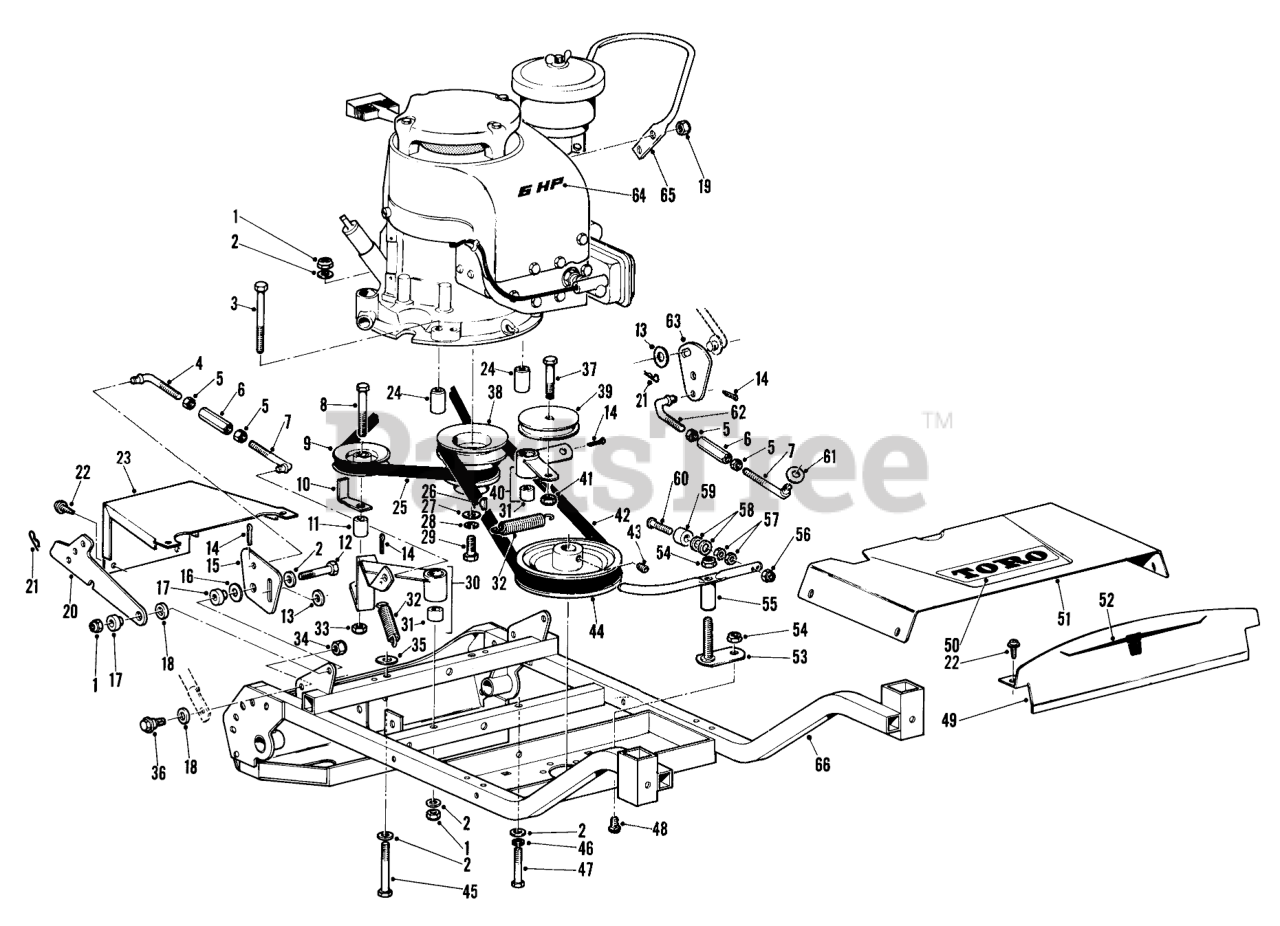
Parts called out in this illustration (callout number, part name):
1	NUT-LOCK, NI
2	WASHER-PLAIN
3	SCREW-HH
4	TRACTION LINK
5	NUT-HEX
6	CONTROL ROD SLEEVE
8	SCREW-HH
9	IDLER PULLEY R
11	Spacer
12	SCREW-HWH, THREAD CUT
13	Spacer
14	PIN-COTTER
15	Bell Crank
16	WASHER
17	PIVOT
18	SPACER
19	NUT-LOCK
20	Latch
21	PIN-COTTER
22	10-16 X 3/8 THDG SCREW
23	Rear Shroud
24	ENGINE PIVOT SPACER
25	V-BELT
26	KEY-WOODRUFF
27	WASHER-FLAT
28	WASHER-LOCK
29	SCREW-HH
30	Arm & Bushing Assy.
31	BUSHING
32	EXTENSION SPRING
33	NUT-LOCK, NI
34	NUT-LOCK, NI
35	WASHER
36	SCREW-SHOULDER
37	Screw
38	Pulley
39	PULLEY B
40	Arm & Bushing Assembly
41	NUT-LOCK
42	CUTTER BELT
43	SCREW-HSH
44	CUTTER PULLEY
45	SCREW-HH
46	WASHER-LOCK
47	SCREW-HH
48	SCREW-CARR
49	Shroud Panel
50	Decal
51	FRONT SHROUD R
52	Decal
53	Base Pivot
54	NUT-LOCK, NI
55	Brake Arm
56	NUT-LOCK, NI
57	NUT-HEX
58	WASHER-FLAT
59	BUMPER
60	10-24X1-1/2 RND HD MS
61	WASHER
62	CUTTER LINK
63	Bell Crank
64	Decal
66	Frame
